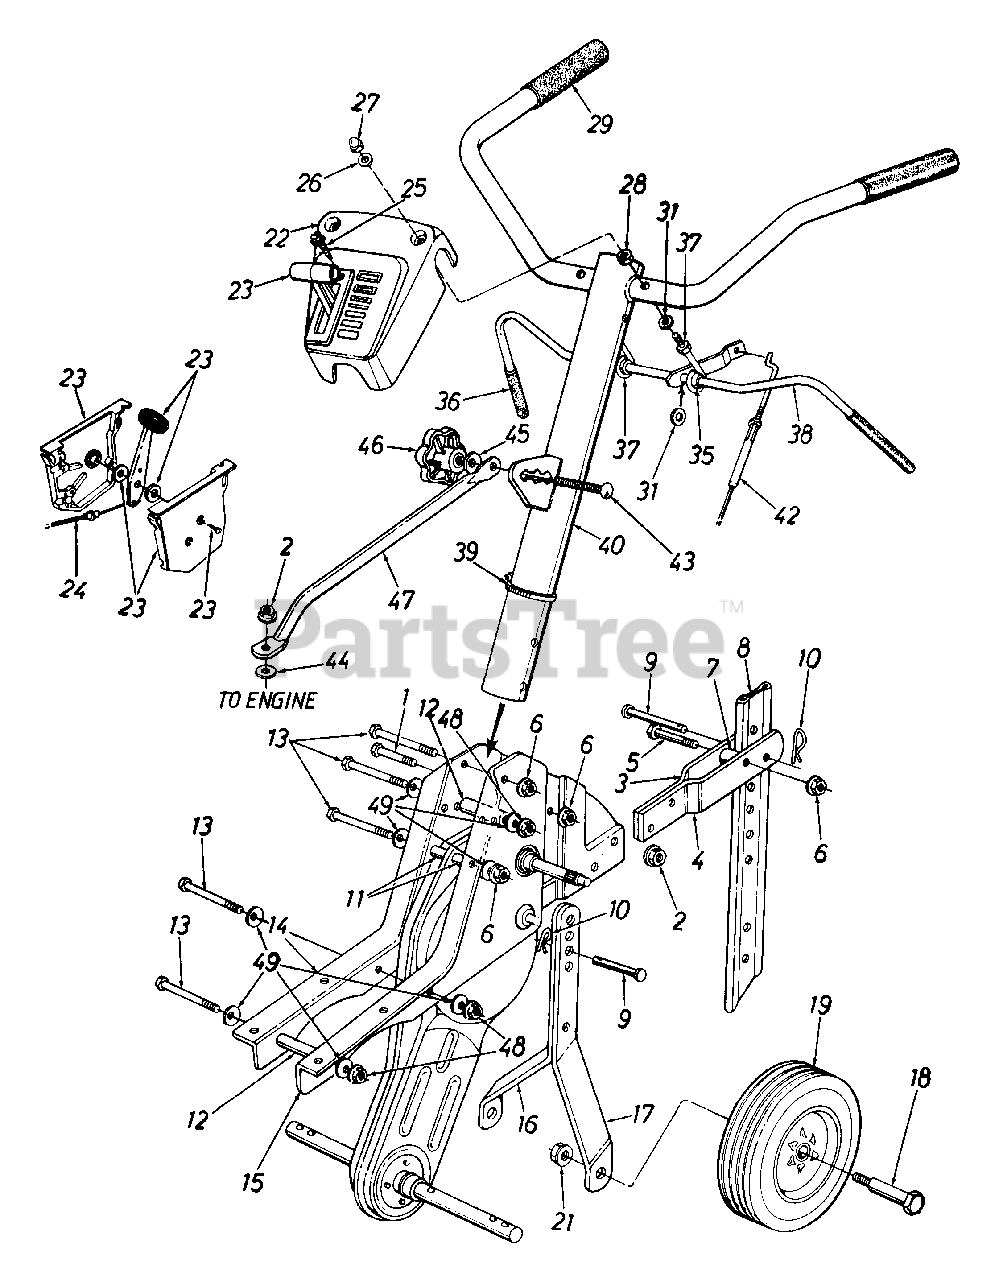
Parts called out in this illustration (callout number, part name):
1	Hex Bolt 5/16-18 x 1.25" Lg.
2	Hex Flange L-Nut 5/16-18 Thd. (Gr. 5)
5	Hex Bolt 5/16-18 x 1.5" Lg.
6	Hex Flange L-Nut 5/16-18 Thd. (Gr. 5)
7	Spacer .32" I.D. x .75" O.D.
9	Clevis Pin .375" I.D. x 1.75" Lg.
10	Internal Cotter Pin
11	Spacer .326" I.D. x .47" O.D.
12	Spacer .322" I.D. x .44" O.D.
13	Hex Bolt 5/16-18 x 2. T5" Lg.
17	Wheel Hanger Brkt.- L.H.
18	Shld. Bolt .498" Dia. x 1.64" Lg.
19	Wheel Ass'y. 8" x 1.T5"
21	Hex Flange L-Nut 3/8-16 Thd. (Gr. 5)
22	Handle Cover
23	Throttle Control Box Ass'y.
24	Throttle Control Wire 30.5" Lg.
25	Truss Mach. AB-Tap Scr. #10 x .5" Lg.
26	Fl-Wash..266" I.D. x .625" O.D.
27	Hex L-Stop Nut 1/4-28 Thd.
28	Hex Nut 1/4-28 Thd.
29	Grip - Handle
31	Fl-Wash..385" I.D. x .62" O.D.
35	Plastic Bushing .38" I.D.
36	Grip - Clutch
37	Clutch Handle Eye Bolt
43	Carr, Bolt 5/16-18 x 1" Lg.
44	Fl-Wash..344" I.D. x 1.12" O.D.
45	Bell-Wash..345" 1.0. x .88" 0.0.
46	Hand Knob
49	Bell-Wash..345" I.D. x .88" O.D.
